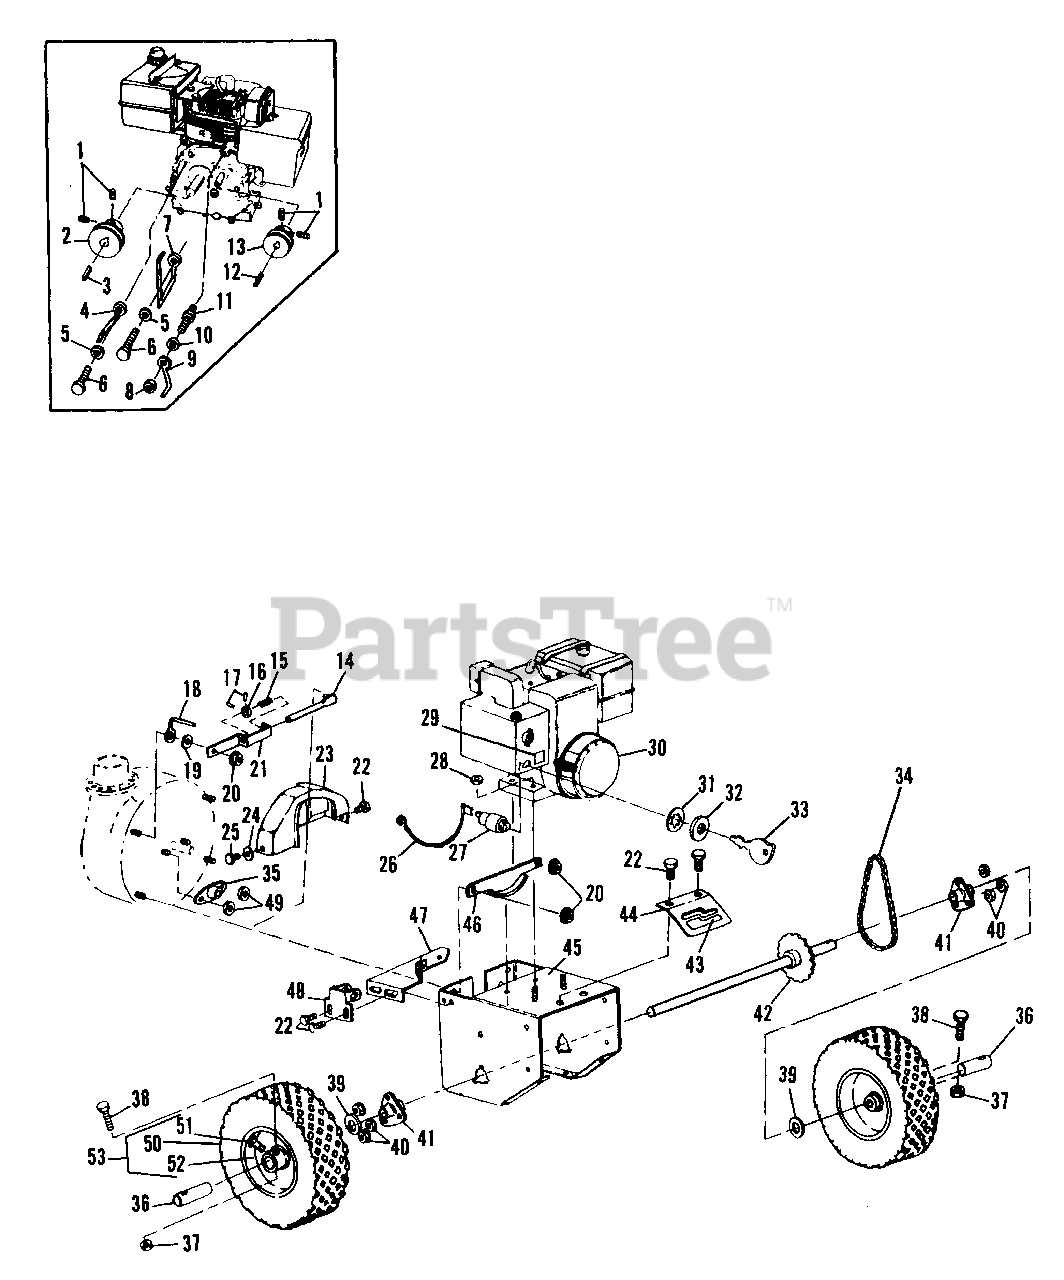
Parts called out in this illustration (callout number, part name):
1	SETSCREW, Nylok, 5/16-18 x 5/16
2	PULLEY, Engine
6	CAPSCREW, Hex Head, 5/16-18 x 3/4
7	BELT GUIDE
8	NUT, Hex Centerlock,1/4-20
10	WASHER
12	KEY, Woodruff
13	PULLEY, Camshaft
15	SPRING, Brake Return
16	SET COLLAR
17	SETSCREW, #10-32 x 1/4
20	NUT, Hex Flange Lock, 3/8-16
21	BRKT., Brake Return Spring
22	SCREW, Hex Head. Taptite, 1/4-20 x 1/2
25	SCREW, Hex Head Taptite, #10-24 x 1/2
26	GROUND WIRE
27	KEYSWITCH (Includes Ref. Nos. 31, 32, 33)
28	NUT, Hex Flange Lock, 5/16-18
29	DECAL, Keyswitch
30	ENGINE, 5 H.P. Tecumseh
31	LOCKWASHER
32	NUT, Hex, 5/8-32
34	CHAIN ASSEMBLY
35	BEARING ASSEMBLY, Impeller
36	SPACER-Wheel
37	NUT, Hex Centerlock, 5/16-18
38	CAPSCREW, Hex Head, 5/16-18 x 1-1/2
40	NUT, Hex Flande Lock, 1/4-20
41	AXLE BEARING
42	AXLE & SPROCKET ASSEMBLY
43	DECAL, Shift
44	BRACKET, Drive Control
45	FRAME ASSEMBLY
46	BELT GUIDE, Lower
47	EXTENSION, Belt Cover
48	BRACKET, Chute Control
49	NUT, Hex Centerlock .375-16
50	TIRE, 4.10/3.50-6
52	VALVE STEM & CAP
53	WHEEL AND TIRE ASSEMBLY
